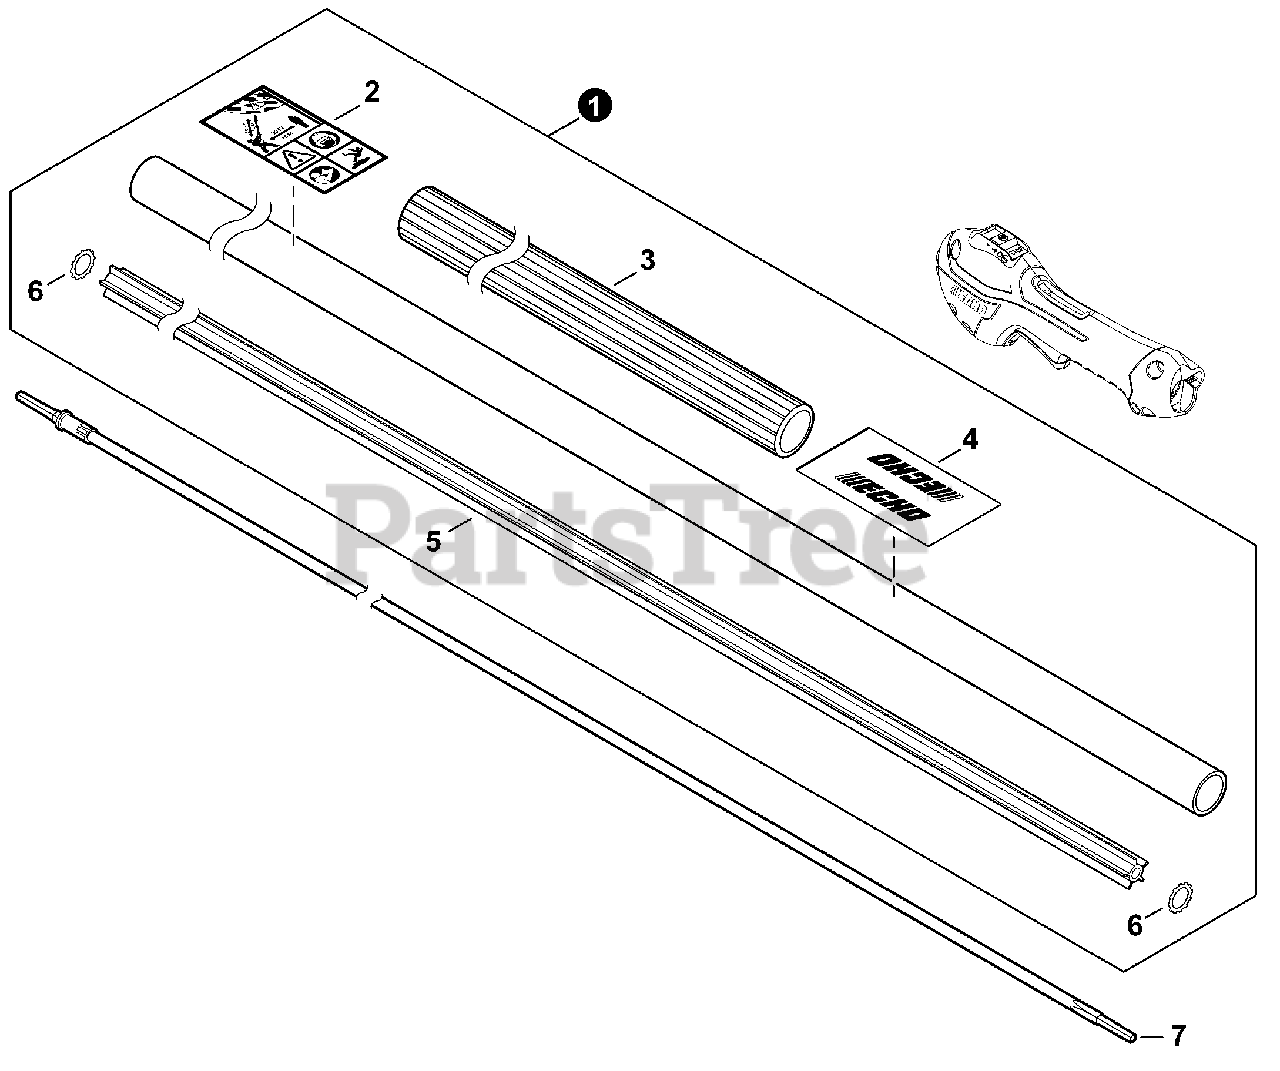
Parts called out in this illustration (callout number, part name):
1	MAIN PIPE ASSY
2	LABEL, CAUTION
3	GRIP, FRONT
4	LABEL, HANDLE LOCATION
5	LINER - FLEXIBLE
7	DRIVESHAFT - FLEXIBLE
